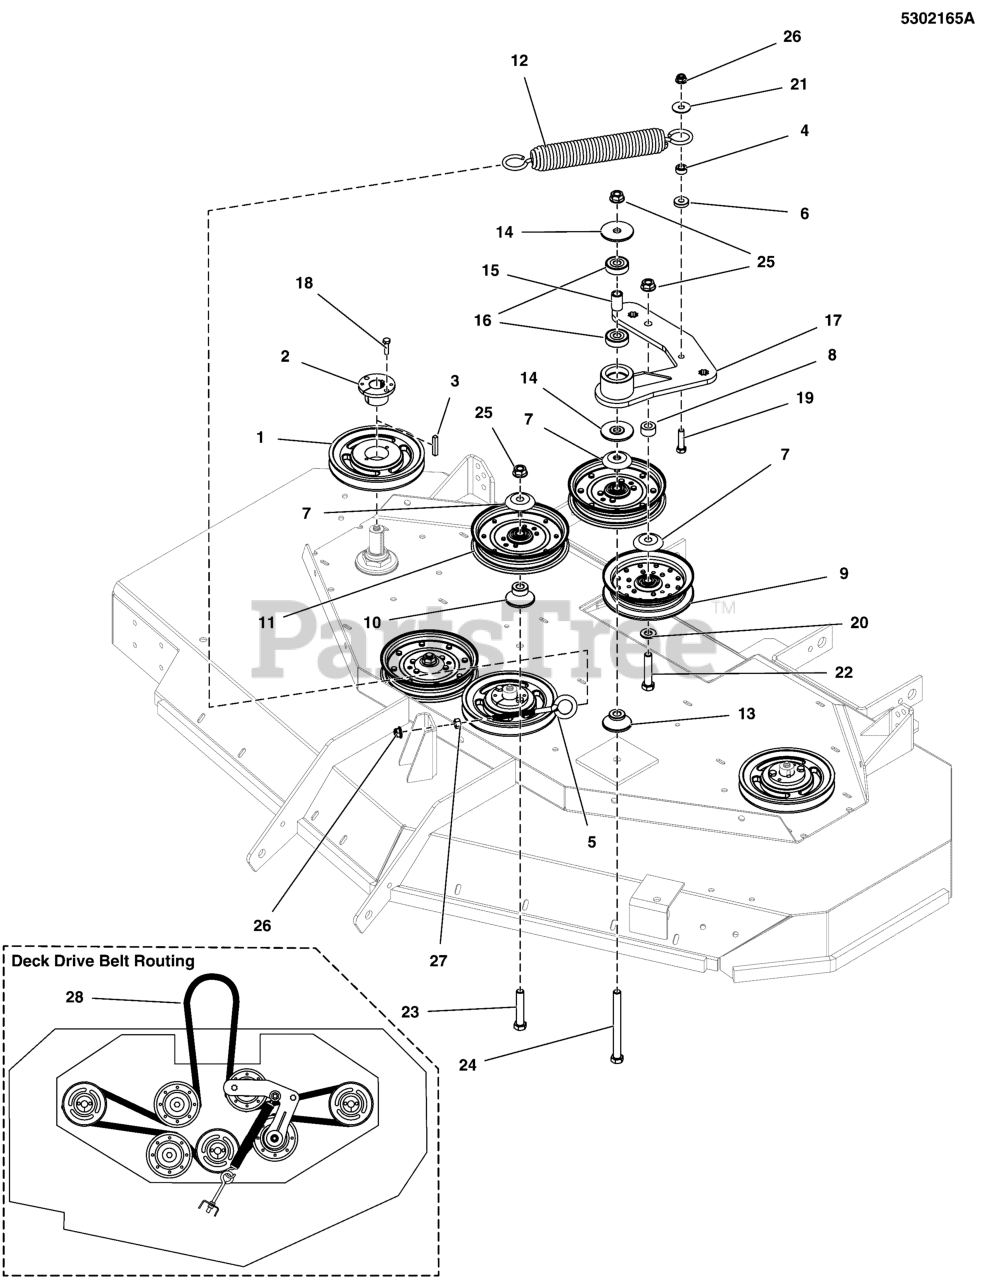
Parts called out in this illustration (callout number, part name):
1	PULLEY, SPINDLE, BH66
2	BUSHING, TAPERED HUB
3	KEY 1/4 SQ X 1 1/2 LONG
4	SPACER, .39 X .75 X .38
5	EYE BOLT, 3/8-16 X 6, 3THRD, 1EYE, CZ
6	SPACER, .39 X 1.00 X .25
7	SHIELD, PULLEY BEARING, CZ
8	SPACER, .52 X 1.00 X .56, CZ
10	IDLER MOUNT
12	SPRING, EXT, 1.5ODX12.25X.234WIRE BLK
13	IDLER MOUNT, .88 HIGH
14	SPACER, IDLER ARM, 1/2 X 2.25
15	SPACER, .51 X .75 X 1.22, PM CZ
16	BEARING, 6203-1/2", SEALED
17	WELD, IDLER ARM - BLK
18	BOLT, 1/4-20 X 1" GD5 CZ
19	BOLT, 3/8-16 X 1-1/2" GD5 CZ
20	WASHER, 1/2 SAE
21	WASHER-3/8 FENDER
22	BOLT, 1/2-13 X 2-1/2" GD5 CZ
23	BOLT, 1/2-13 X 2-3/4 GD5 CZ
24	BOLT, 1/2-13 X 5-1/2 GD5 CZ
25	NUT, Hex Flange, Nylock, 1/2-13
26	NUT, 3/8-16 HEX NYLOCK FLANGE
27	NUT, 3/8-16 HEX
28	BELT, 5V, 197.90"EL, LRG ARAMID, WRP, RC
